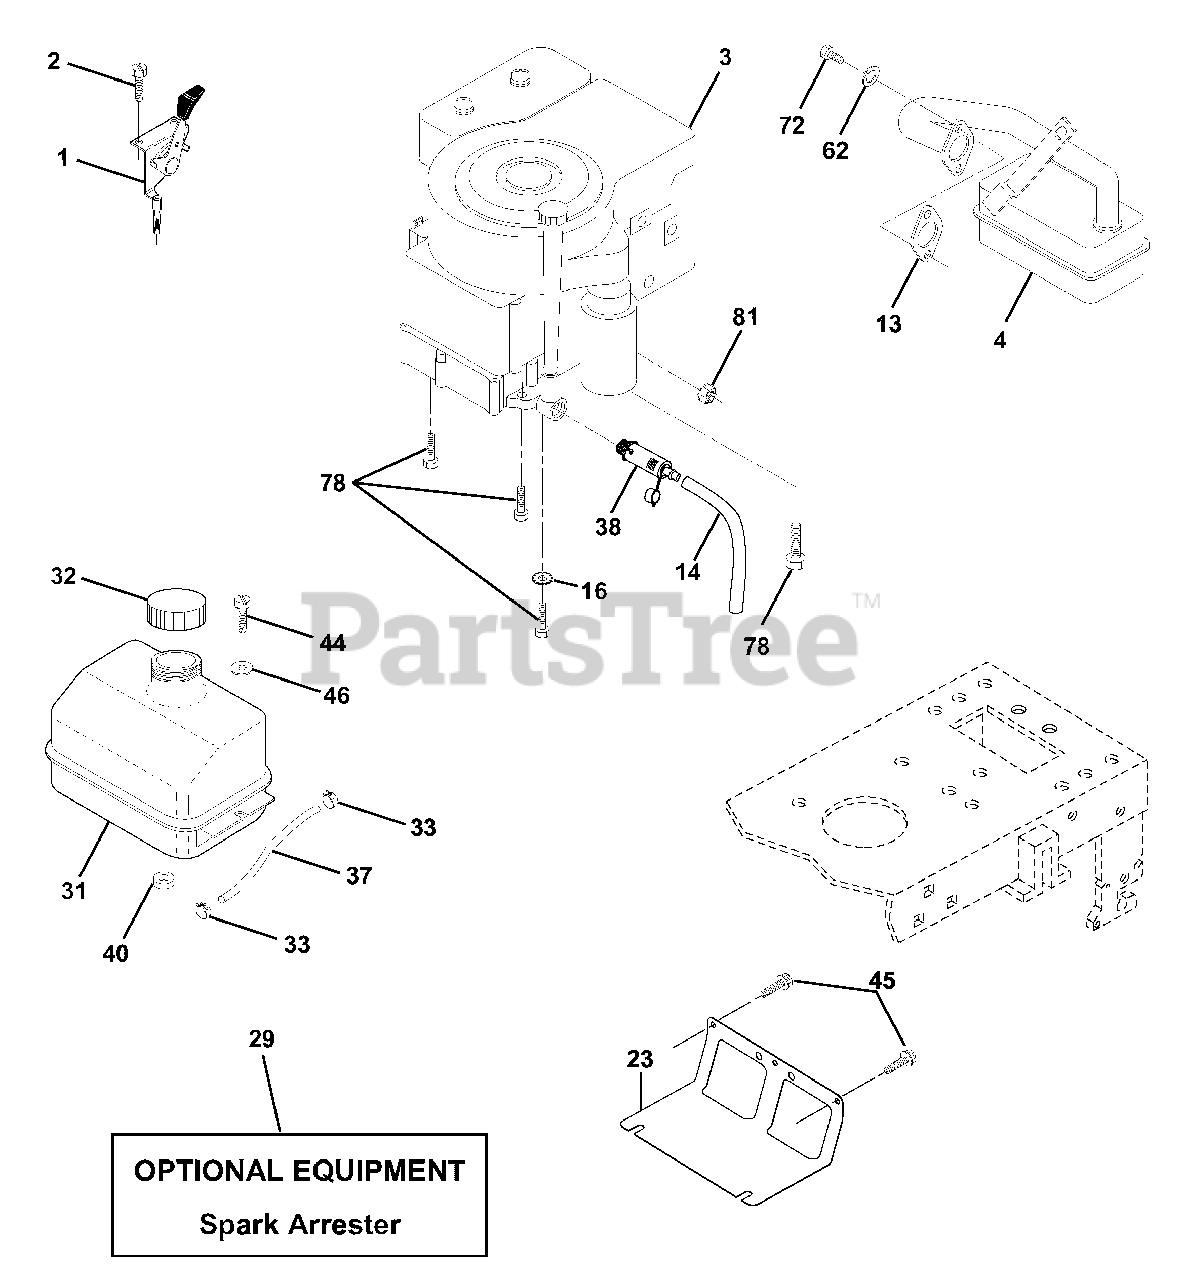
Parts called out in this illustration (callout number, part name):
1	Control Throt/Ch 23.5 Lh Flag
2	Screw Hex Thd Cut 1/4-20x5/8 T
4	Muffler Exhaust B&S Lt
13	Gasket 1 313 Id Tin Plated
14	Tube Drain Oil Easy
16	Washer Lock Ext Tooth 3/8
23	Shield Browning/Debris Guard
29	Arrestor Spark
31	Tank Fuel 1 25 Fr
32	Cap Asm Fuel W/sym Vented
33	Clamp Hose Blk
37	Line Fuel 20"
38	Plug Oil Drain
40	Bushing Snap Nyl Blk Fuel Line
44	Screw Hexwsh Thdrol 1/4-20x3/4
45	Screw Hex Wsh Thdrol 3/8-16
46	Washer 9/32 X 7/8 X 16ga
62	Washer Lock Hvy Hlcl Spr 5/16
72	Screw Hexhd Cap 5/16-18x3/4
78	Screw Thdrol 3/8-16x1-1/4
81	Nut Keps Hex 1/4-20 Unc
